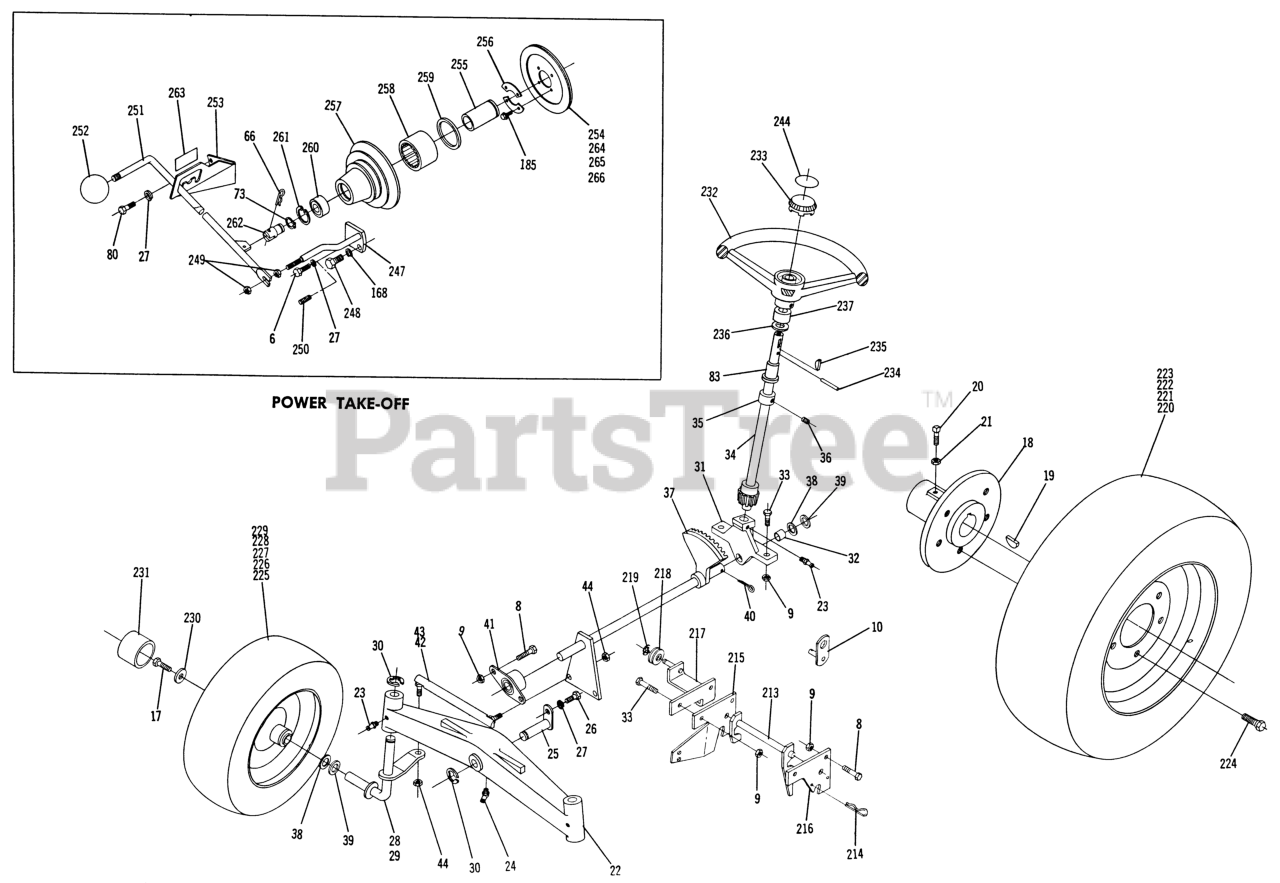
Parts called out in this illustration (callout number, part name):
1	Frame
2	Hoodstand
3	Bolt Carriage 1/4-20 x 3/4
4	Nut, 1/4-20
5	Cover-Dust
6	Bolt 5/16-18 x
7	Nut-Nylok
8	Bolt 3/8-16 x 1
9	3/8-16 E.S.
10	Cam Arm
11	Bolt 3/8-16 x 3/4
12	Washer
13	Lockwasher
14	Pulley Trans
15	Set Screw
16	WOODRUFF KEY
17	Bolt 3/8-16 x 7/8
18	Hub Wheel
19	WOODRUFF KEY
20	Screw-Set
21	3/8-16 Jam Nut
22	AXLE-FRONT
23	Zerk
24	FITTING-GREASE
25	PIN AND PLATE ASM
26	Bolt Hex 5/16-18
27	Lockwasher
28	R.H. Spindle
29	L.H. Spindle
30	E-RING
31	Support
32	BEARING-BRONZE
33	Bolt 3/8-16 x 1
34	ASSY UPPER STEER R
35	Collar
36	Set Screw Nylok
37	Assy-Steering
38	WASHER-SHIM
39	WASHER
40	Cotter Pin
41	BEARING-FLANGED
42	Tie Rod-R.H.
43	Tie Rod-L.H.
44	Locknut 3/8-24
45	Assy.-Idler Arm
46	Arm Clutch Rod Pivot
47	SPIROL PIN
48	PULLEY-IDLER
49	Bolt 3/8-16 x 1 5/8
51	Rod Clutch
52	Rod-Brake
53	Trunnion
54	Cotter Pin
55	Spring
56	Ass-y Lock-Brake
57	Pedal
58	Lift Lever
59	LOWER PLUNGER R
60	PLUNGER ROD
61	Roll Pin
62	SPRING-COMPRESSION
63	Guide-Rod
64	Cap
65	HANDGRIP
66	Hairpen
67	Quadrant
68	ROD-LIFT CONTROL
69	KNOB-LIFT CONTROL
70	Conduit
71	Hitch
72	Pin
73	RING-SNAP, EXTERNAL
74	SPACER
75	BATTERY BOX ASSY R (NS)
76	LINK BATTERY CLAMP
77	Nut-Nylok
78	Housing
79	Support-Fuel Tank
80	Bolt Hex 5/16-18
81	Bolt 1/4-20 x 5/8 Whizlock
82	Tape
83	Bushing
84	Grommet
85	Panel
86	SPEED NUT
87	Screw-Self Tap #10-16
88	Plug Button
89	Filter
90	Fuel Hose
91	Fuel Tank
92	Clamp-Tank
93	Cap
94	Bolt 1/4-20 x 1 1/4
95	Nut Square
96	S/A FUEL VALVE
97	Fuel Hose
98	Clip
99	Washer
100	Nut 5/16-18
101	CLAMP CORBIN 7/16
102	Engine 10 H.P. Lauson "B"
103	Engine-12 H.P.-R12
104	SPACER
105	Bolt, 3/8-16 x 1/2
106	Base Engine
107	Fuel Hose
108	Nipple 3/8 x 5
109	ELBOW-STREET
110	Cap
111	Bolt 3/8-16 x 7/8
112	Muffler
113	Nipple 1" x 1 1/2
114	Elbow 90 X 1
115	Clamp
116	Nipple-Special
117	PULLEY
118	Key
119	Choke-Control
120	Ass-y.-Throttle
121	Control Choke
122	Control Throttle
123	Lockwasher 9/16
124	RING NUT
125	SWITCH
126	Nut
127	Lockwasher 6/16
128	Insulator
129	Key-EL
130	Cigar Lighter
131	Knob & Plug
132	SHELL CLAMP
133	Socket
134	Nut #8-32
135	Lockwasher
136	Clip
137	Screw 1/4-20 x 3/8 Whizlock
138	Special Nut
139	Fuse
140	ASSY FUSED CONN
141	Battery
143	Wire-Ground
144	Harness-Wiring
145	Cover Battery Term
146	ASSY REFLECTOR HOUSI
147	WIRE ASSY
148	SPRING
149	BULB
150	Lens
151	Pan HD Swage
152	Switch
153	Harness
154	SPEED CLIP
155	CONNECTOR 3 WIRE
156	CLIP-WIRE
157	Tail Light
158	Base
159	Lens
160	Bulb
161	Mounting Pad
162	CONNECTOR 2 WIRE
163	Screw, 10-32 X 5/8
164	Nut #10-32
165	Lockwasher #10
166	Belt Guard
167	Bolt Hex 7/16-4 x 3/4
168	Lockwasher 3/8
169	Washer 7/16
170	Bracket
171	Bolt, 5/16-18 x 1/2
172	Footrest R.H.
173	Footrest L.H.
174	BRACKET
175	Bolt-Carriage 5/16-18
176	Latch Fender
177	Spring
178	NYLINER BUSHING
179	Pin
180	Hairpin
181	BRACKET FENDER LATCH
182	Bolt-Hex 1/4-20
183	Stop-Fender Latch
184	Cover Plate
185	Bolt, 1/4-20 Whizlock
186	Fender
187	BUSHING-FLANGED
188	Bolt 3/8-24 x 7/8 Hex
189	SPACER
190	GROMMET
191	Seat Base
192	Spacer
193	Bolt-Car. 5/16-18 x 1
194	Nut, 5/16-18
195	Cushion Seat
196	Back Cushion
197	Knob 8 HP
198	Hood
199	Bracket-Grill Pivot RH
200	NYLINER BUSHING
201	Bolt Hex 5/16-18 x 3/4
202	Rod-Pivot
203	Bracket-Grill Pivot LH
204	LEVER HOOD LATCH
205	KNOB
206	SPIROL PIN
207	Roller
208	Nut-Hi Crown
209	SPEED NUT
210	Rod Latch
211	Hood Ornament
212	SPEED NUT
213	ASSY LATCH & SHAF R
214	Hairpin
215	MOUNTING BRACKET R
216	PLATE-MTG BRKT LH R (NS)
217	ASSY BRACKET AND R
218	ROLLER
219	Lock Rod
220	Wheel and Tire
221	Wheel
222	Tire
223	VALVE TUBELESS
224	Lug Nut
225	Wheel-Complete
226	WHEEL
227	Bearing
228	TIRE TURF SAVER 16X6.50-8
229	VALVE TUBELESS
230	WASHER
231	Hub Cap
232	Steering
233	CAP INSERT
234	ROLL PIN 1/4 X 1-1/4
235	Key
236	WASHER-BOWED
237	COLLAR
238	Decal-Hood
239	Decal-Raider 12
241	Decal Shift Pattern
242	Deal-Seat Latch
243	Decal
244	Decal
245	Pin-Tool
246	V BELT
247	PLATE & ROD ASSEM R
248	Bolt, 7/16 14 x 1
249	Nut Conlok 3/8-16
250	Set Screw 3/8-16 x 3/4
251	ROD ASSY
252	Knob
253	Bracket
254	L/A CLUTCHPLATE&FACI
255	RACE-BEARING
256	RETAINER
257	Clutch Housing
258	Seal
259	SEAL-OIL
260	Bearing
261	Ring-Snap
262	SHAFT
263	DECAL
264	Clutch Plate
265	CLUTCH FACING
266	RIVET-BRASS
267	Engine-10 H.P.-R10
268	Engine-8 HP-Lauson
269	Harness-Wiring
270	Assembly-Choke Control
271	Tank-Fuel
272	HOLD DOWN WIRE
273	SPRING-EXTENSION
